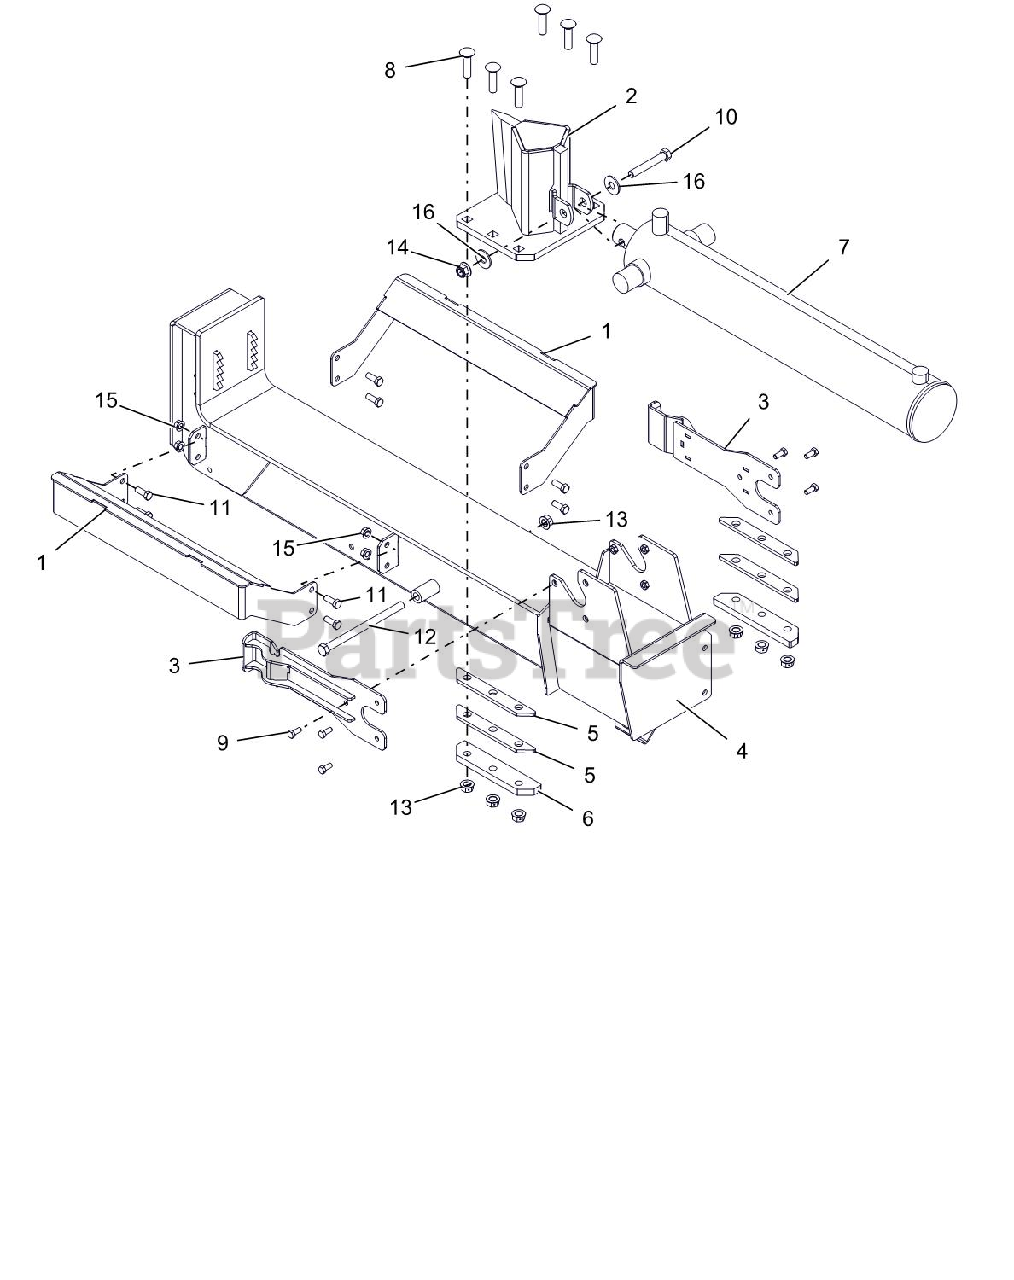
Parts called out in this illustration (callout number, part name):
1	WLDMT, CRADLE, LOG SPLITTER
2	WMT, WEDGE - SPLITTER
3	WLDMT, PLATE - STRIPPER
4	WMT-BEAM-LOG SPLITTER
5	SPACER, WEDGE
6	RETAINER,WEDGE
7	CYLINDER, 4.0" W/DECALS
8	BLT-RDHDSQNKFTH.50-13X2 G8YWZC
9	@BLT-HEX .31-18X.75 GR5 YWZC
10	@BLT-HEX .50-13X3.25 GR5 YWZC
11	@BLT-HEX .38-16X1.00 GR5 YWZC
12	@BLT-HEX .50-13X7.50 GR5 YWZC
13	NUT-LK-CTR-FLG .50-13 YWZC
14	@NUT-LK-NYL-FLG .50-13 YWZC
15	@NUT-LK-TOP-FLG .38-16 YWZC
16	@WSHR-FL-STL.563X1.38X.109YWZC
